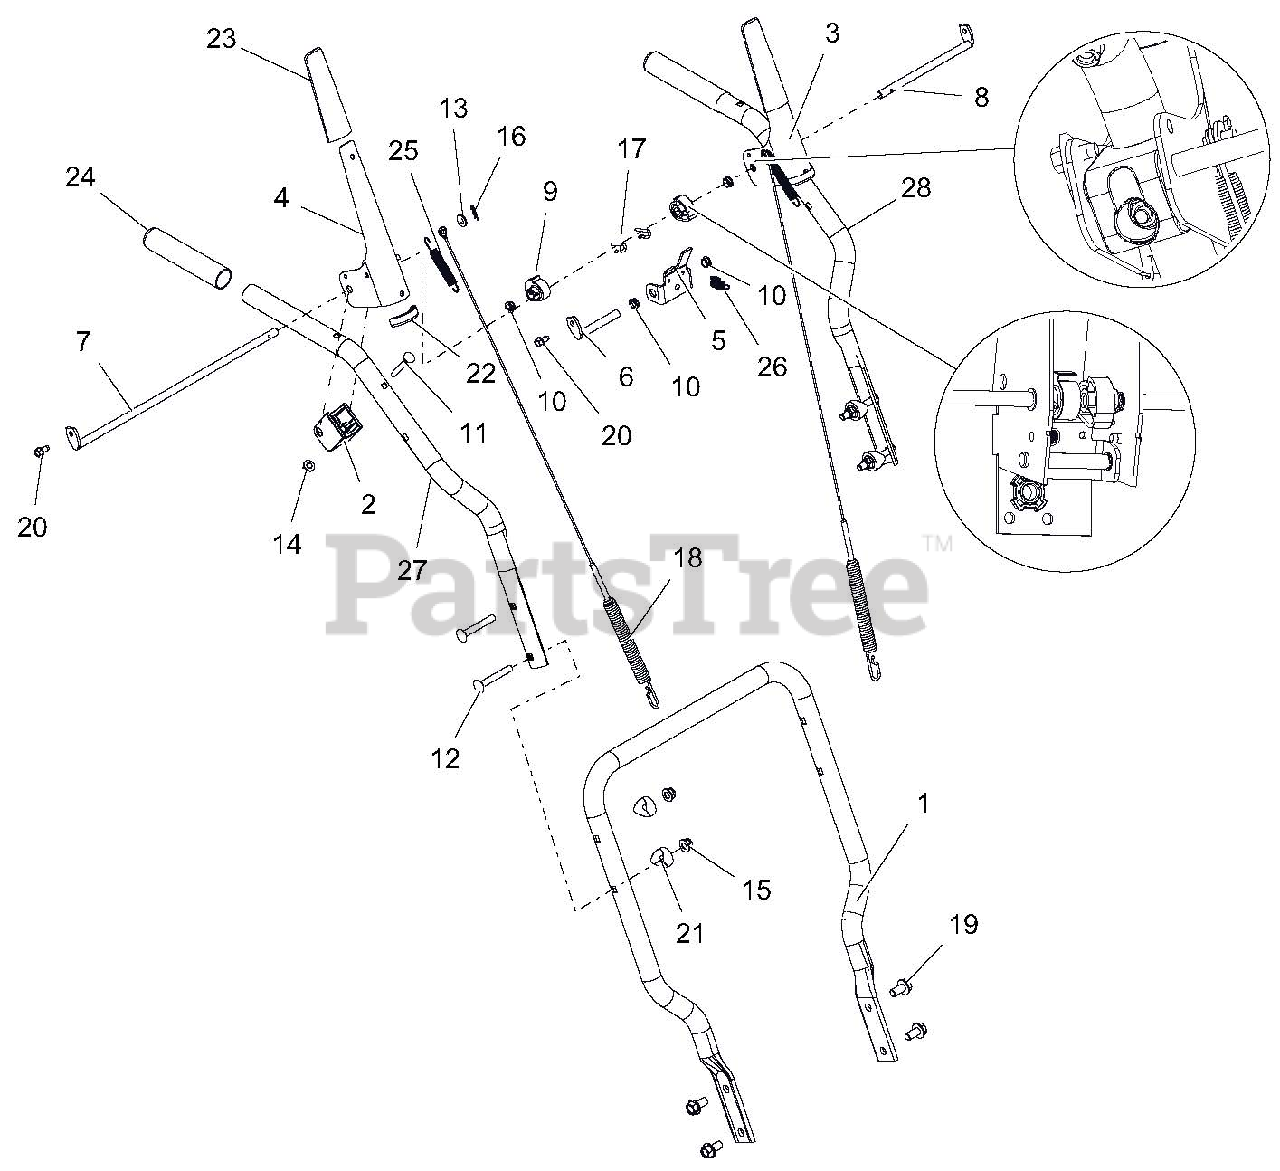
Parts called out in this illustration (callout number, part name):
1	HANDLEBAR, LOWER (COMPACT)
2	BLOCK, CLUTCH PADDLE
3	LEVER, CLUTCH-LH
4	LEVER, CLUTCH-RH
5	BRACKET, INTERLOCK ARM
6	ROD, PIVOT - INTERLOCK
7	ROD, PADDLE MOUNT - LONG
8	ROD, PADDLE MOUNT - SHORT
9	CAM, INTERLOCK
10	BUSHING, POLYLINER-.38 SNAPIN
11	BLT-RDHDXLSQNK .25-20X2.0 G5YZ
12	@BLT-RDHDSQNK .31-18X2.25 G5YZ
13	@WSHR-FL-STL.281X.62X.065 YWZC
14	@NUT-LK-TOP-FLG .25-20 YWZC
15	@NUT-LK-NYL-FLG .31-18 YWZC
16	PIN-HAIR INT .06X.18X.77
17	PIN, SPRING CLIP
18	CABLE, AUGER & UPPER TRACTION
19	BLT-SERHFWH .38-16X.75 YWZC
20	SCR-TAP .25-20X.50 HWH TR YWZ
21	SPACER, HANDLEBAR
22	EDGING, CLUTCH PADDLE - 2.00"
23	CLUTCH PADDLE SLEEVE - GRAY
24	HANDLE GRIP
25	SPRING, EXTENSION
26	SPRING-EXT .047X.438X1.45
27	HANDLEBAR, UPPER - RH
28	HANDLEBAR, UPPER - LH
